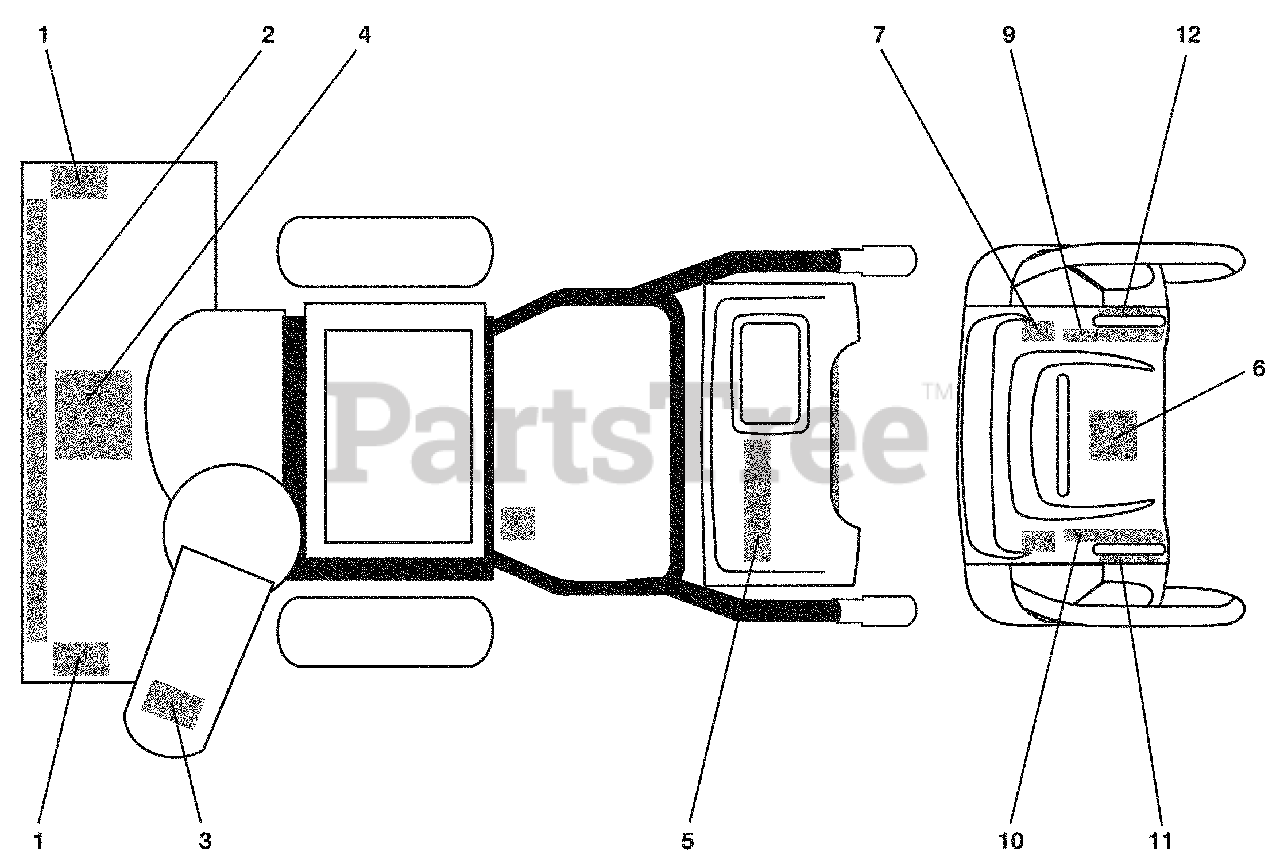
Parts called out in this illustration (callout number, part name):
1	DECAL, DANGER
2	DECAL, AUGER, 10527SB-LSb HUSQ. USA
3	DECAL, DANGER, DEFLECTOR
4	DECAL, DANGER
5	DECAL, CONSOLE, 10527SB-LSb HUSQ. USA
6	DECAL, INSTRUCTION
7	DECAL, AUTOMATIC
9	DECAL, SPEED CONTROL
10	DECAL, REMOTE DEFLECTOR
11	DECAL, LH TRIGGER
12	DECAL, RH TRIGGER
